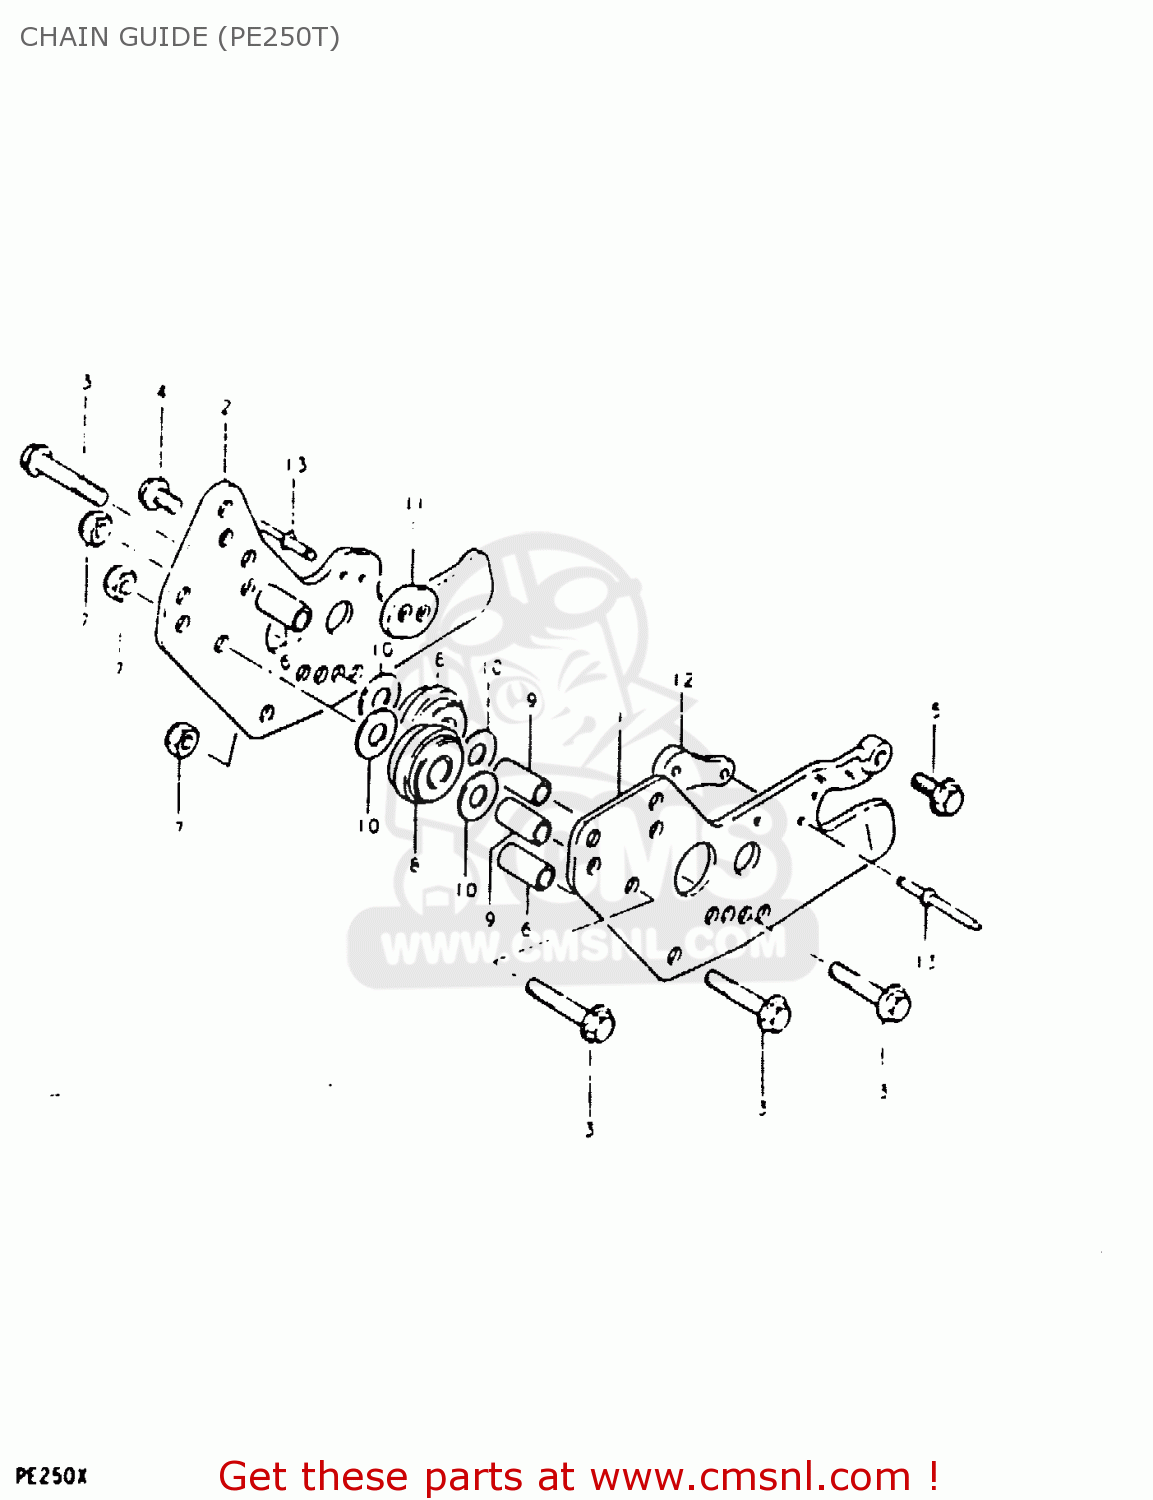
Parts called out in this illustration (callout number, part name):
1	PLATE,CHAIN GUIDE,OUTER
2	PLATE,GUIDE CHAIN
3	BOLT
4	BOLT
5	BOLT
6	SPACER(6.8X10X24.2)
7	NUT
8	ROLLER,CHAIN GUIDE
9	SPACER,CHAIN GUIDE ROLLER
10	WASHER
11	PAD,DRIVE CHAIN GUIDE
12	PAD,DRIVE CHAIN GUIDE
13	RIVET
